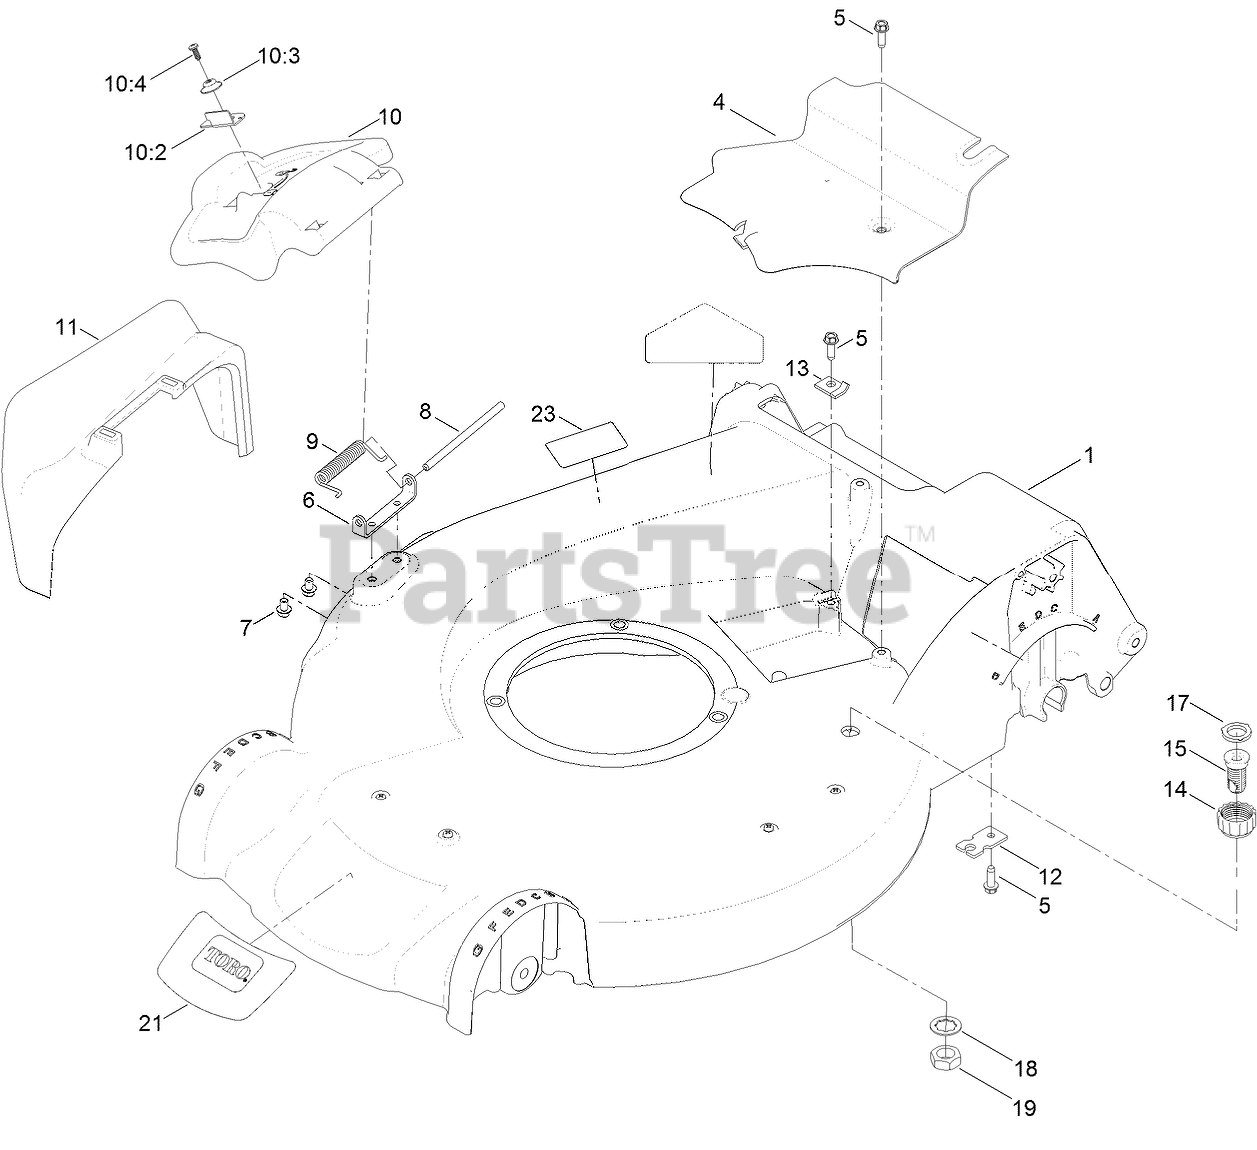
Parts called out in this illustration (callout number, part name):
1	HOUSING ASM
4	COVER-BELT
5	SCREW-HWHTF
6	BRACKET-COVER
7	SCREW-HWH
8	ROD-COVER
9	SPRING-TORSION
10	DISCHARGE DOOR ASM
10:2	LATCH-DOOR
10:3	CAP-DOOR
10:4	SCREW-PLASTITE
11	CHUTE-DISCHARGE, SIDE
12	BRACKET-CABLE, TRACTION
13	CLAMP-CABLE
14	COUPLING-HOSE, WASHOUT PORT
15	PORT-WASHOUT
17	WASHER-SEAL, WASHOUT PORT
18	WASHER-TOOTH, INTERNAL
19	NUT-JAM
21	DECAL-DECK
23	DECAL-PLACEMENT, FOOT
